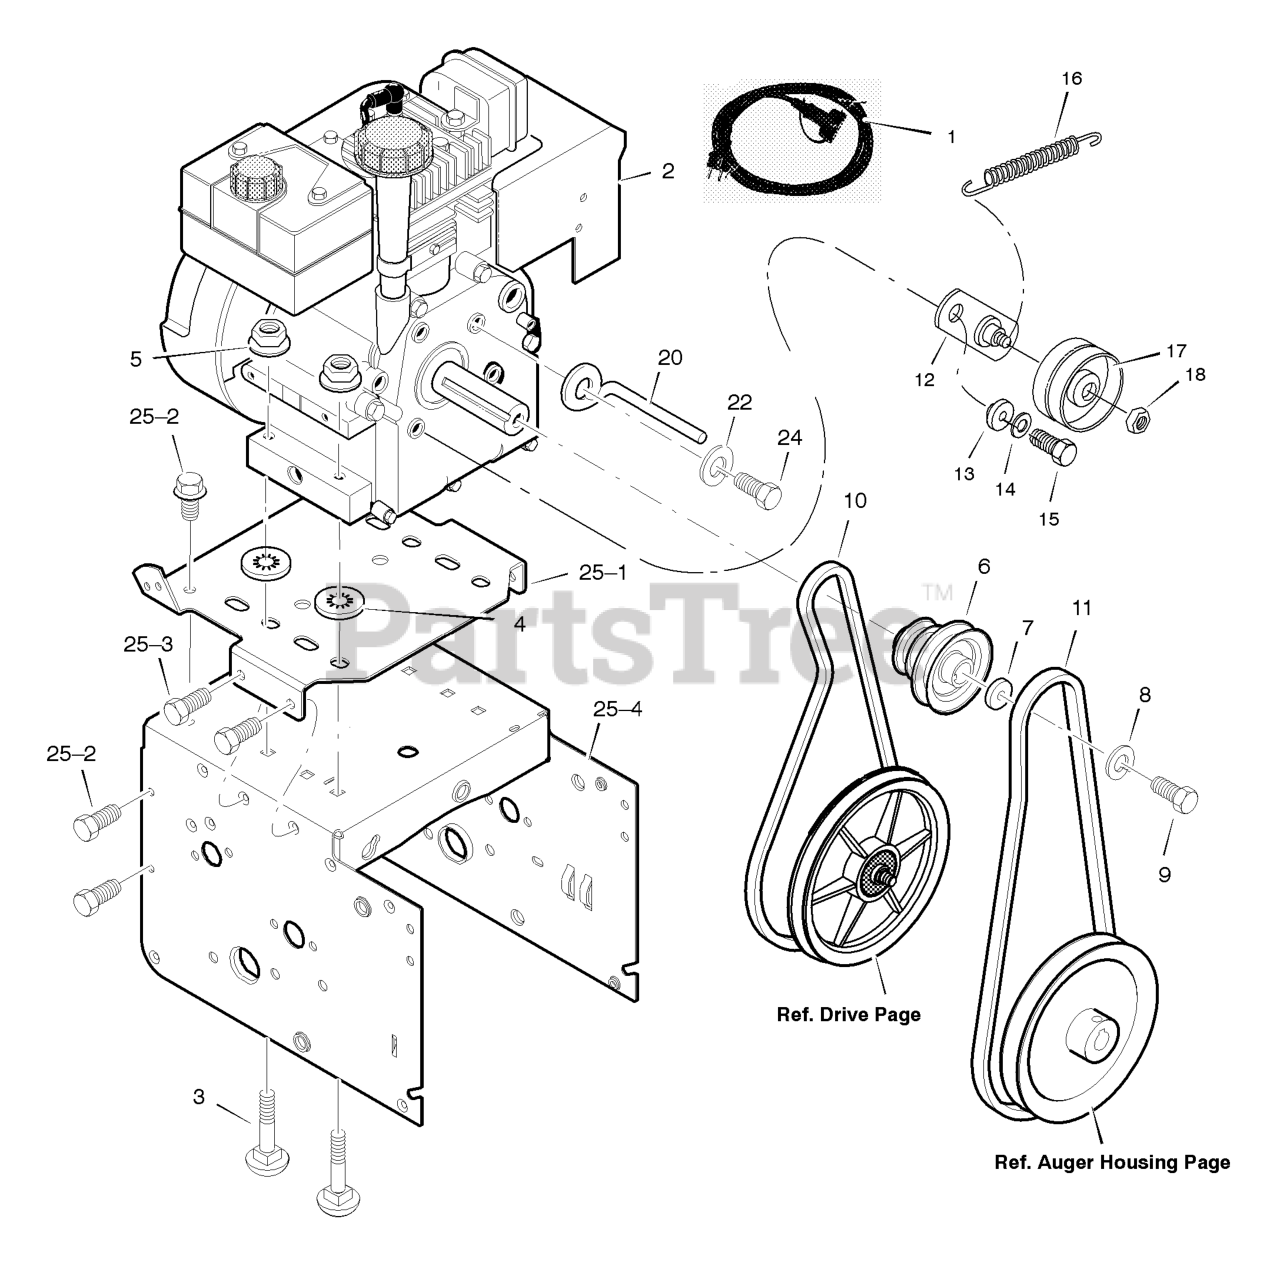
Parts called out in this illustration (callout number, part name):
1	CORD, Electric, 10FT. 110V
2	ENGINE
3	BOLT, CARRIAGE 5/16-18
4	RETAINER, PUSH
5	NUT 5/16-18
6	PULLEY, ENGINE
7	WASHER
8	WASHER .38ID
9	SCREW, 3/8-24 x 1.00
10	BELT, AUGER
11	BELT, DRIVE
12	BRACKET ASSEMBLY, IDLER
13	BUSHING, IDLER BRACKET
14	WASHER, SPLIT
15	SCREW 5/16-24 X 0.75
16	SPRING, IDLER TRACTION DRIVE
17	PULLEY, IDLER
18	NUT, JAM 3/8-16
20	GUIDE, BELT
22	WASHER .31X.58X.08
24	SCREW, 5/16-24 x 0.75
25-1	PLATE, ENGINE MOUNT
25-2	SCREW, TAP 1/4-20 X .63
25-3	SCREW, TAP 5/16-18 X .50
25-4	FRAME, MOTOR BOX
